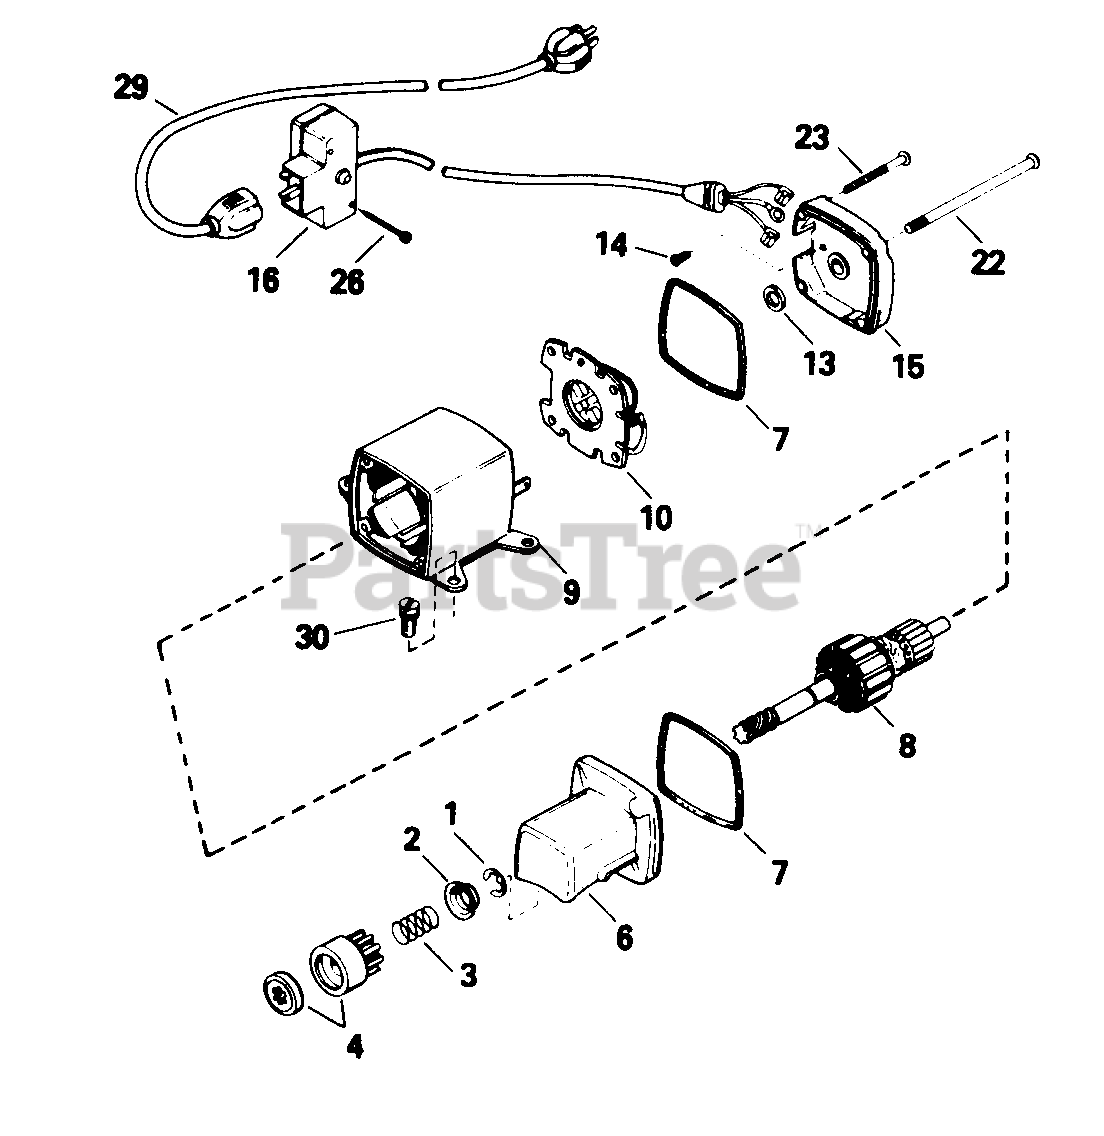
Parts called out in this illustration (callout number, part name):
1	Ring, Retainer
2	Retainer, Spring
3	Spring, Anti-Drift
4	Nut & Gear
6	Cap Ass'y., Drive End
8	Armature
9	Housing Ass'y.
10	Card Ass'y., Brush
13	Washer, Thrust
14	Screw, Ground
15	Cap Ass'y., Commutator End
16	Box Ass'y., Switch
22	Bolt, Case
23	Screw, Grounding
26	Screw, Hex Hd. Self-Tap, 6-32 x 2-1/2
29	Cord, Extension (10' 6")
30	Screw, Hex Hd. Self-Tap, 1/4-20 x 11/16
